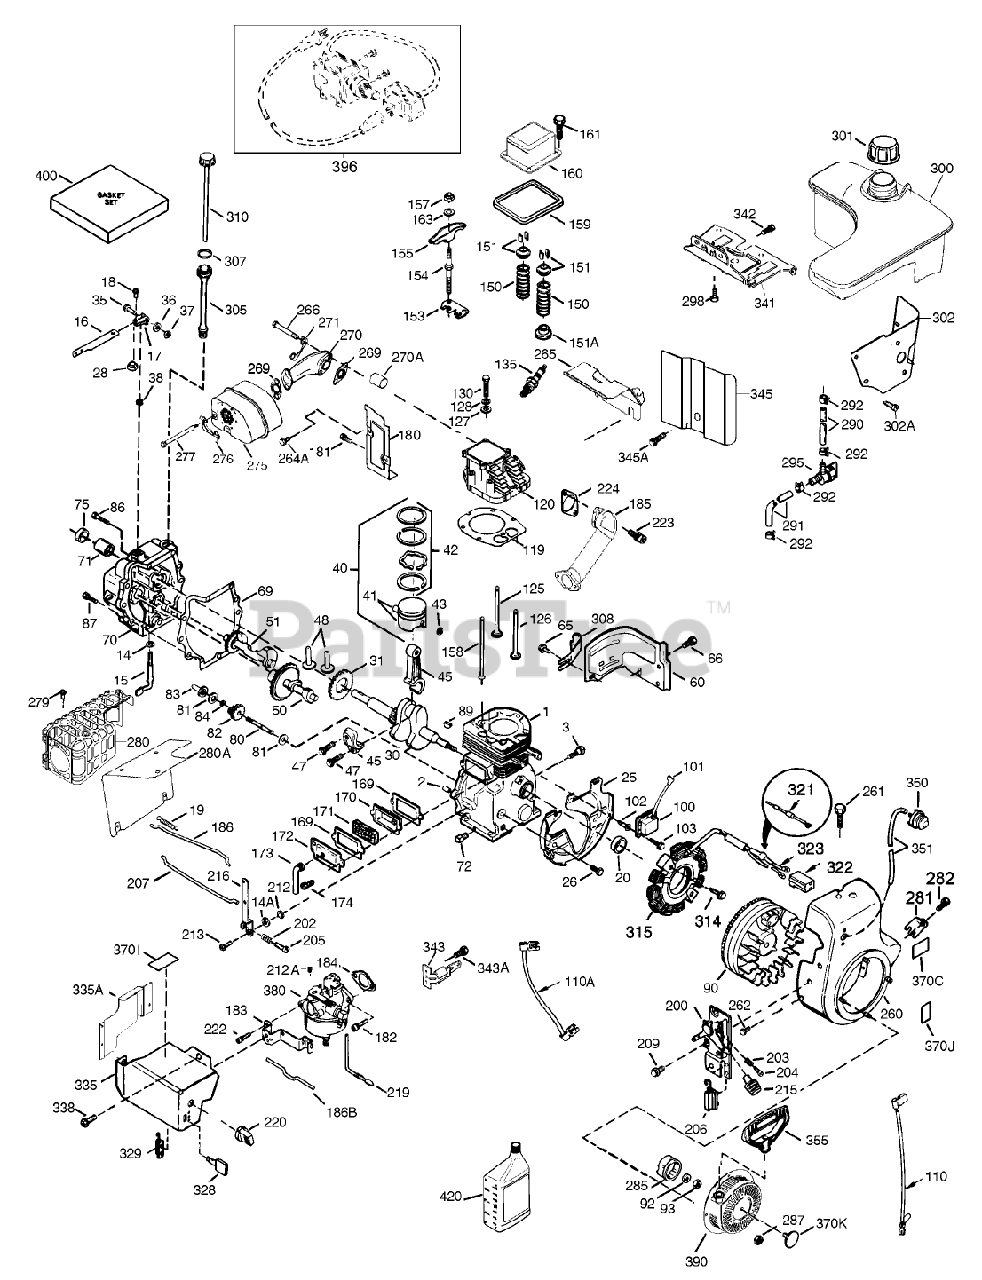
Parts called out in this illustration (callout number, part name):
1	Cylinder (Incl. 2, 20, 72 80)
2	Pin-Dowel
3	Screw (1/4-20x1/2)
14	Washer-Flat
14A	Washer
15	Governor Rod (Incl. Ref.#14 38)
16	Governor Lever (Incl.212A)
17	Clamp-Lever, Governor
18	Screw (T-15, 8-32x7/16)
19	Throttle Spring
20	Seal-Oil
25	Baffle-Housing, Blower
26	Screw (1/4-20x19/32)
28	Nut-Lock
30	Crankshaft
31	Counterbalance Gear
35	Screw
36	Washer-Lock
37	Nut-Lock
38	Ring-Retaining
40	Piston Pin and Ring ASM (STD)
40	Piston Pin and Ring ASM (.010)
40	Piston Pin and Ring ASM (.020)
41	Piston Pin Ass-y(Std.)(Incl. 43)
41	Piston Pin Ass-y (.010" OS)(Incl. 43)
41	Piston Pin Ass-y.(.020" OS)(Incl. 43)
42	Ring Set (STD)
42	Ring Set (.010)
42	Ring Set (.020)
43	Retaining Ring-Piston Pin
45	Connecting Rod ASM (Incl. Ref. #47)
47	Bolt-Rod, Connecting
48	Lifter-Valve
50	Camshaft
51	Counterbalance Weight
60	Extension-Housing, Blower
65	Screw (10-24 x 9/16)
66	Screw
69	55072/75/86/89 TWO
70	Cylinder Cover (Incl. Ref. #14, 15, 38, 71, 75)
71	2025A77 WIZARD ROTA
72	Plug-Drain, Oil (SQH 1/4-18)
75	Seal-Oil
80	Governor Shaft
81	Washer
82	Gear-Asm Governor
83	Governor Spool
84	Ring-Retaining
86	Screw (1/4-20x1-3/16)
87	Screw (1/4-20x1-11/16)
89	Key-Flywheel
90	Flywheel (W/Ring Gear)
92	Washer-Belleville
93	Nut-Flywheel
100	Ignition-Solid State
101	Cover-Spark Plug
102	Stud-Mounting, Solid State
103	Screw (T-15, 10-24 x 15/16)
110	Wire-Ground
110A	Wire-Ground
119	Cylinder Head Gasket
120	Cylinder Head (Incl. 151A)
125	Valve-Exhaust (STD)
125	Valve-Exhaust (1/32)
126	Valve-Intake (STD)
127	Washer-Flat
128	Washer-Belleville
130	Screw (5/16-18 X 2-1/2)
135	Spark Plug-Resistor (R N 4C)
150	Spring-Valve
151	Keeper-Spring, Valve
151A	51106 GILSON ROTARY
153	Guide-Rod, Push
154	Stud-Arm, Rocker
155	Arm-Rocker
157	Nut-Jam
158	Rod-Push
159	Gasket-Cover, Rocker Arm
160	Cover-Arm, Rocker
161	Screw
163	Washer
169	Gasket-Cover, Valve
170	Body-Breather
171	Element-Breather
172	Cover-Valve
173	Tube-Breather
174	Screw
180	Extension-Housing, Blower
181	Screw (10-24 x 9/16)
182	Screw (T-30, 1/4-20 X 27-32)
183	Bracket-Choke
184	Gasket-Carburetor To Intake Pipe
185	Pipe-Intake
186	Governor Link
186B	Spring-Choke
200	Bracket-Control (Incl. Ref. #203, 204 and 206)
202	Compression Spring
203	Spring-Compression
204	Screw (T-10, 5-40x7/16)
205	Screw
206	Terminal
207	Choke Link
209	Screw (10-32 x 1/2)
212	Bushing
212A	Bushing
213	Screw
215	Knob-Control
216	Lever-Adjusting
219	Rod-Choke
220	Knob-Control
222	Screw (10-32 x 1/2)
223	Screw (T-30, 5/16-18 X 7/8)
224	Gasket-Pipe
260	Blower Housing
261	Screw (1/4-20 X 5/8)
262	Screw
264A	Screw
265	Cover-Head, Cylinder
266	Screw (5/16-18 X 1-9/32)
269	Gasket-Manifold, Exhaust
270	55107 SNWTHWR ATTCH
270A	Liner-Port, Exhaust
271	Plate-Locking
275	Muffler
276	Locking Plate
277	Screw (5/16-18 X 4-1/2)
279	Screw (10-32 x 1/2)
280	Cylinder (Incl. 2, 20 150)
280A	Shield-Heat, Radiation
281	Screw
282	Screw (8-32 x 3/8)
285	Cup-Starter
287	Nut and Lock Washer (1/4-28)
290	Line-Fuel
291	Line-Fuel (8.62)
292	Clamp-Line, Fuel
295	Valve-Shut Off, Fuel
298	Screw (1/4-15x7/8)
300	Fuel Tank (Incl. 292 and 301)
301	Cap-Fuel
302	Extension-Tank, Fuel
302A	Screw (10-32 x 1/2)
305	Tube-Fill, Oil
307	O-Ring
308	Clip-Tube, Fill
310	Dipstick
314	Screw (1/4-20 x 3/4)
315	Alternator Coil (3/5)(Incl. 321-323)
321	Diode
322	Body-Connector
323	Terminal
328	Key-Ignition
329	Terminal
335	Spring
335A	Cover-Carburetor
338	Screw (10-32 x 1/2)
341	Bracket-Tank, Fuel
342	Screw (5/16-18 X 7/8)
343	Bracket-Switch, Key
343A	Screw (8-32 x 23/64)
345	Baffle-Heat
345A	Screw (10-32 x 1/2)
350	Primer ASM
351	Line-Primer
355	Handle-Starter, Mitten Grip
370C	Decal-Primer, International Symbol
370I	Decal-Warning (Bilingual)
370J	Decal-Choke
370K	Decal-Tecumseh Logo for Top of Recoil Starter
380	Carburetor (Incl. Ref.# 184)
390	Starter-Rewind
396	Electric Starter Motor (120 Volt)
400	Gasket Set (Incl. Items Marked PK in Notes) Incl. part #-s 27272A (1), 27 896A (2), 33263 (1), 33515A (1), 34265 (1), 35317 (1), 35683 (1), 35762 (2), 35952 (1), 36333 (1), 36352 (1), 36358 (1), 36930 (1), 36932 (1), 36942 (1)
